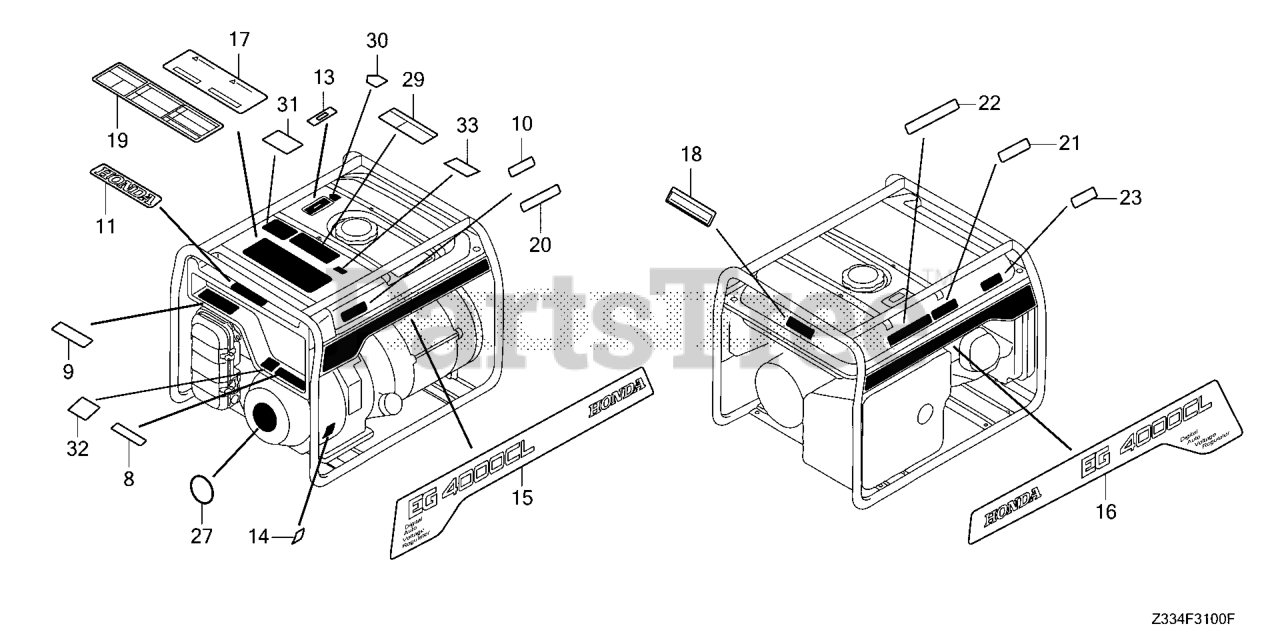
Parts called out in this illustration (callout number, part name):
8	MARK, FR. EMBLEM (EG4000CL)
9	MARK, OPERATION
10	LABEL, OIL ALERT
11	MARK, HONDA
13	PLATE, FUEL INDICATION
14	MARK, OIL CHECK
15	MARK, EMBLEM (EG4000CL) (L. SIDE)
16	MARK, EMBLEM (EG4000CL) (R. SIDE)
18	MARK, SPEC
19	LABEL, OPERATOR WARNING (AG)
22	LABEL, EX. WARNING
27	MARK, HONDA
29	LABEL, FUEL WARNING (ENGLISH)
30	MARK, DIRECTION (AG)
31	LABEL, SHUTOFF CAUTION (AG)
32	MARK, CAUTION (GFCI)
33	LABEL, WARNING
